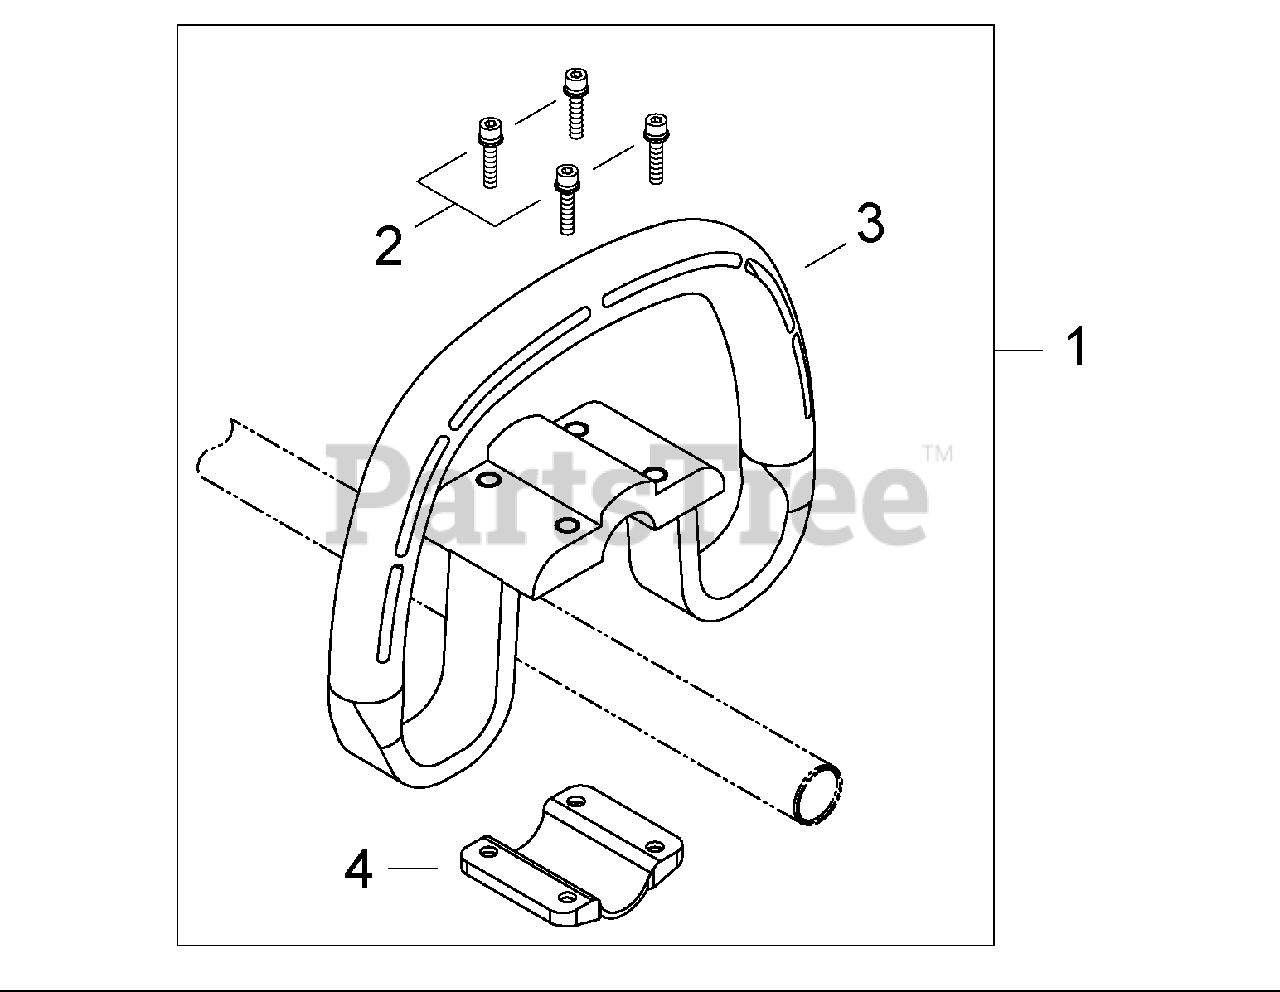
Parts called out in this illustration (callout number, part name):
1	HANDLE ASSY
2	BOLT M5×25
3	HANDLE, SUPPORT
4	BRACKET, MOUNTING
